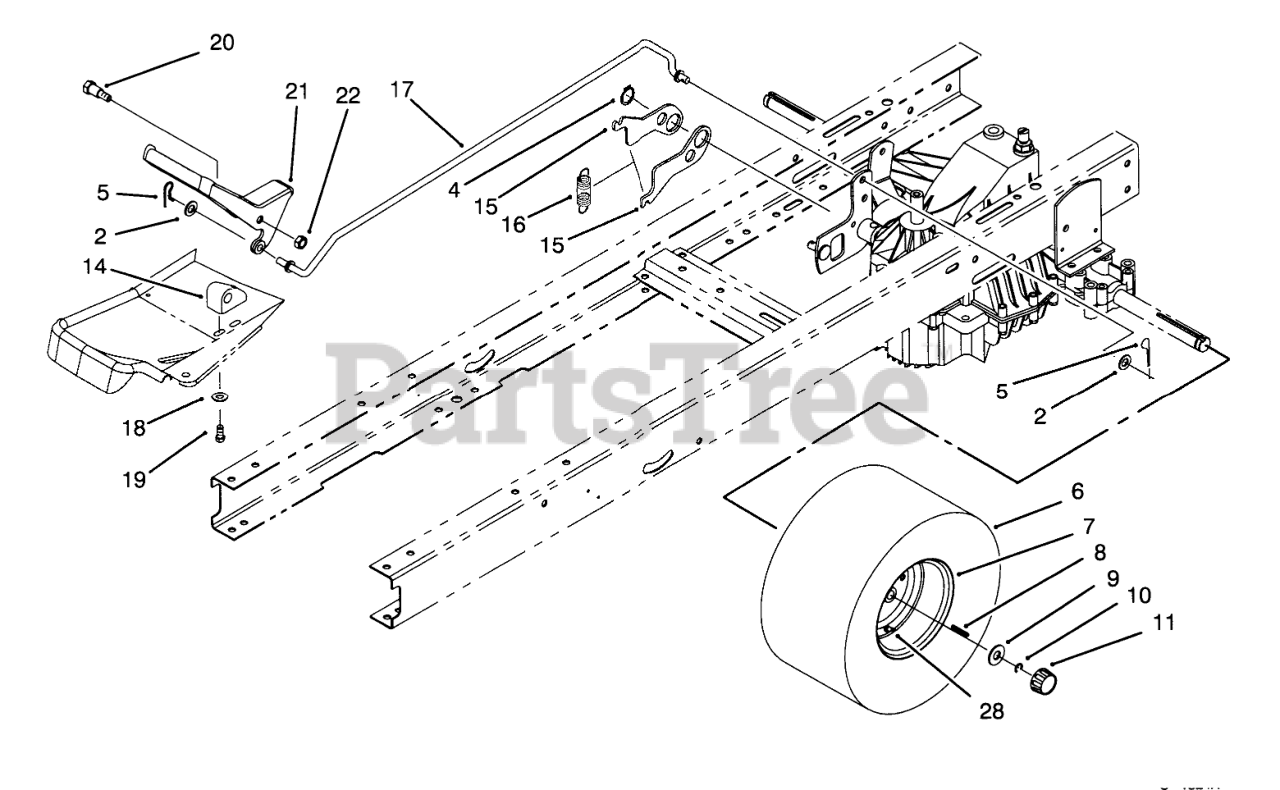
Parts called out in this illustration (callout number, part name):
2	WASHER-PLAIN
4	RING-SNAP
5	PIN-COTTER
6	TIRE 18 X 9.50 X 8
8	KEY-SQUARE
9	WASHER-PLAIN
10	E-RING
11	CAP-HUB
14	BLOCK-PIVOT
15	NEUTRAL RETURN LEVER
16	SPRING-EXTENSION
17	SPEED CONTROL ROD
18	WASHER-FLAT
19	SCREW-PLASTITE
20	SCREW-SHOULDER, HH
21	PEDAL SPEED CONTROL
22	NUT-LOCK, NI
28	STEM-VALVE
